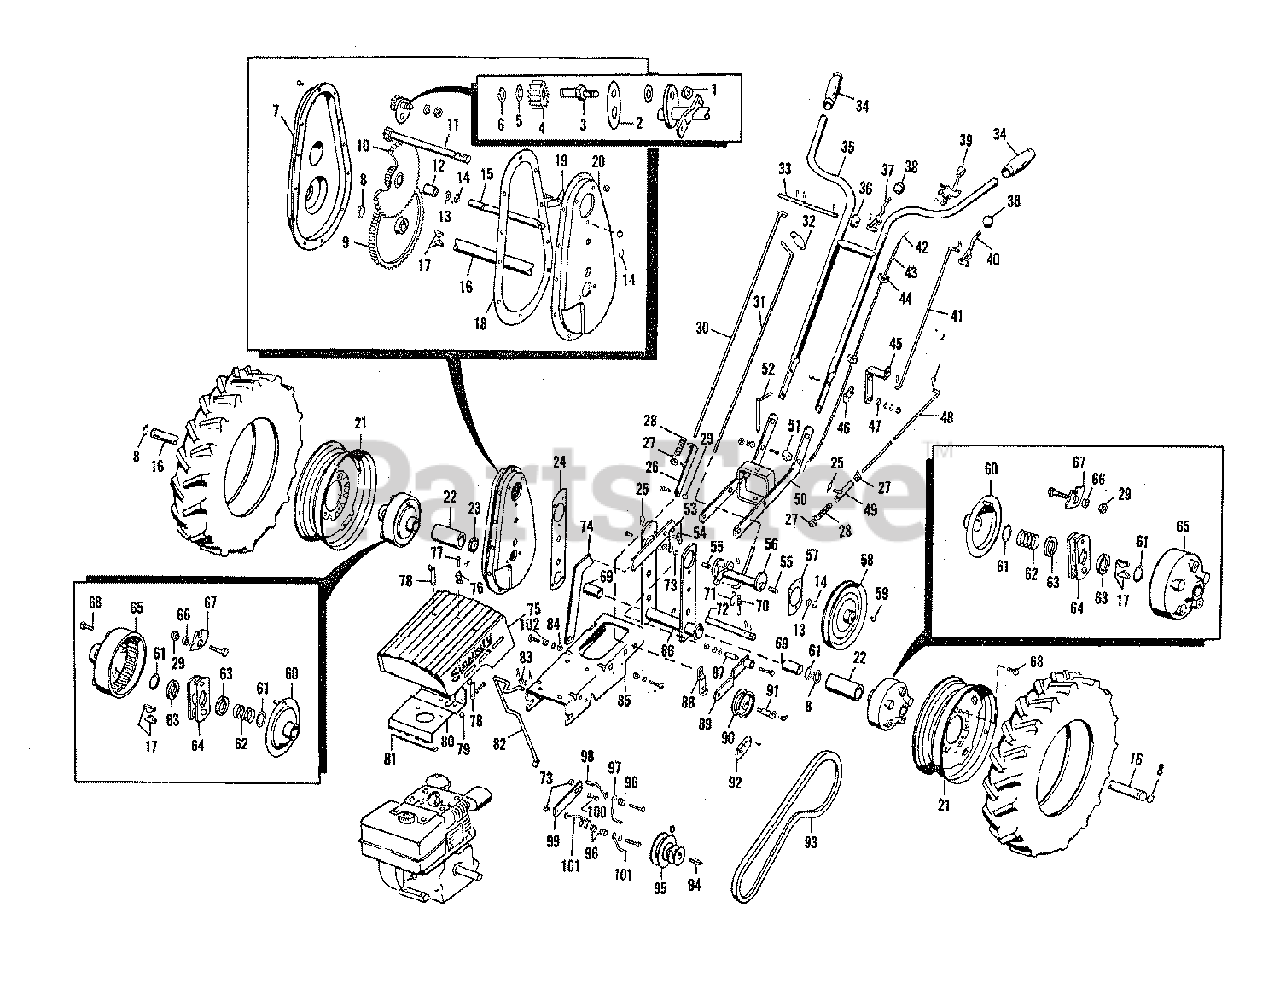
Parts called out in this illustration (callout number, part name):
1	NUT, Full, Hex, L.H.
3	REVERSIBLE PINION STUUD
4	REVERSE PINION ASSEMBLY
5	REVERSE PINION WASHER
6	RETAINING RING
7	GEAR CASE COVER ASSEMBLY
8	RETAINING RING
9	DRIE GEAR
10	INTERMEDIATE GEAR ASSEMBLY
11	PINION w/SHAFT ASSEMBLED
12	INTERMEDIATE PINION BEARING
14	RETAINING RING
15	INTERMEDIATE SHAFT
17	HI-PRO KEY, HP-608
18	GEAR CASE GASKET
19	DRAG SPRING
20	GEAR CASE
22	RUBBER TUBE
23	RETAINING WASHER
24	BEARING HOUSING GASKET
25	SPRING CLIP
26	CLUTCH ROD GUIDE ASSEMBLY
30	CLUTCH ROD
31	REVERSE ROD
32	REVERSE ROD GRIP
33	LEVER SHAFT
34	HANDLE GRIP
35	HANDLE ASSEMBLY
36	REVERSE ROD GUIDE
37	R.H. CLUTCH LEVER ASSEMBLY
38	CLUTCH LEVER BALL
39	THROTTLE CONTROL LEVER ASSEMBLY
40	L.H. CLUTCH LEVER ASSEMBLY
41	UPPER IDLER ROD
42	THROTTLE WIRE
43	THROTTLE CABLE
44	CABLE CLIP
45	LOWER CLUTCH LEVER
46	LEVER STOP
48	LOWER CLUTCH ROD
49	ROD SOCKET ASSEMBLY
50	FRAME ASSEMBLY
51	THROTTLE CABLE CLAMP
52	HITCH PIN ASSEMBLY
56	BEARING HOUSING ASSEMBLY
58	TRANSMISSION PULLEY
60	RATCHET CAGE COVER ASSEMBLY
62	AXLE SPRING
63	AXLE WASHER
64	RATCHET CAGE ASSEMBLY
65	WHEEL HUB
66	RATCHET CAGE SPACER
69	AXLE BEARING
70	REVERSE LEVER SPRING
71	SPRING EXTENSION
75	HOOD ASSEMBLY
76	HOOD SPRING
80	HOOD BRACKET ASSEMBLY
81	HINGE PIN
82	STAND ASSEMBLY
83	STAND SPRING
86	AXLE HOUSING ASSEMBLY
87	IDLER LEER SPACER
88	IDLER LEVER EXTENSION
89	IDLER LEVER ASSEMBLY
90	IDLER PULLEY ASSEMBLY
91	IDLER PULLEY PIN
92	SERIAL No. PLATE
93	V" BELT - 44" Long`
94	ENGINE PULLEY KEY
95	ENGINE PULLEY KEY
97	BELT STOP
98	BELT STOP
99	BELT STOP HOLDER
100	HOLDER SCREW
101	BELT STOP
102	SPACER - Lock Bar
